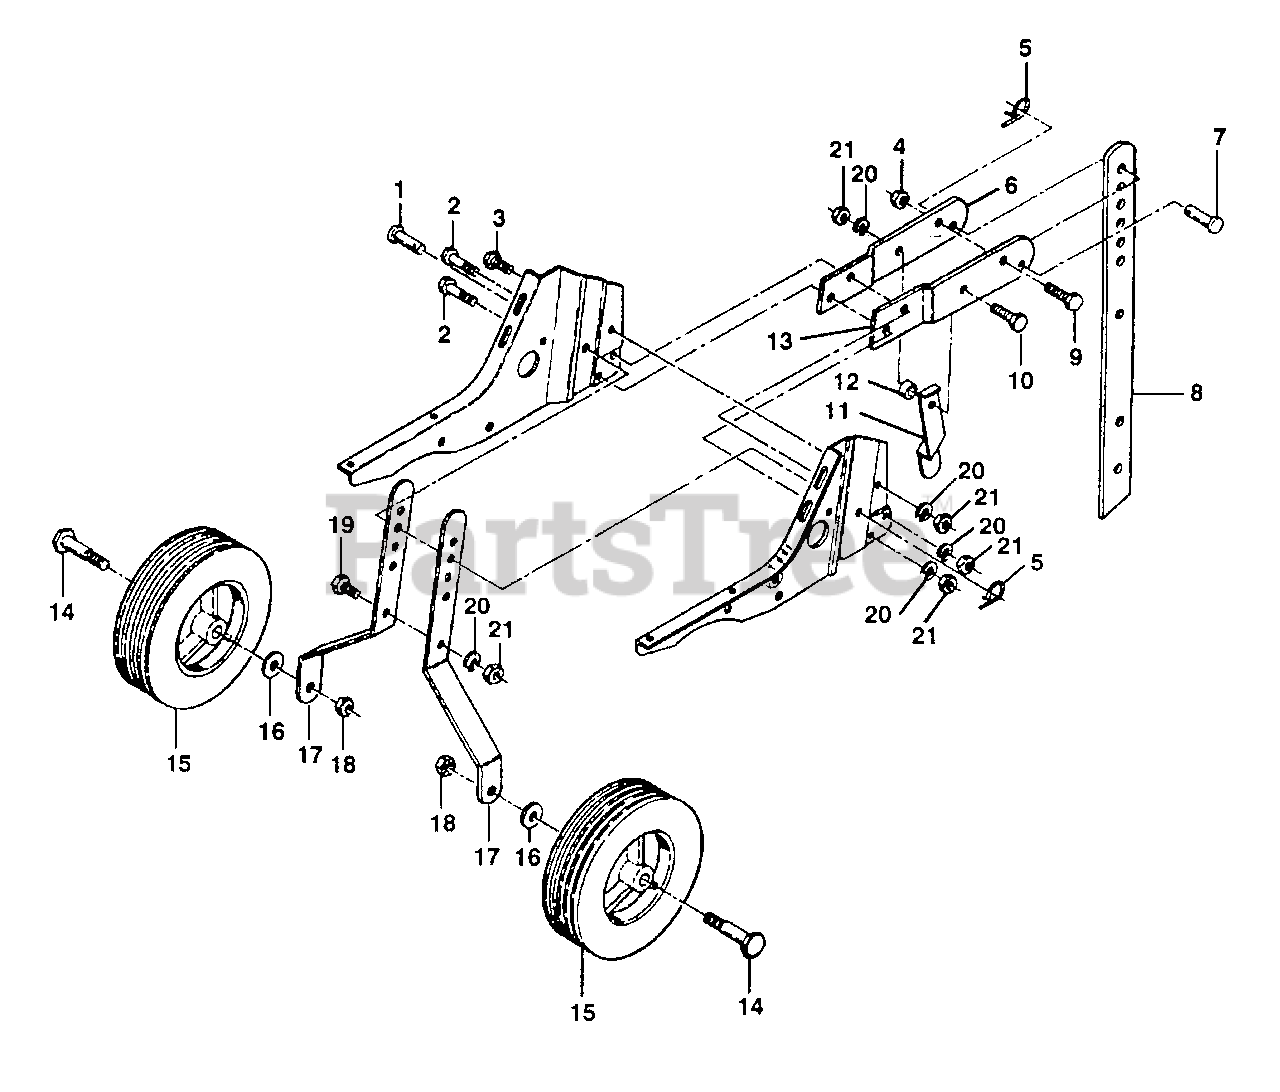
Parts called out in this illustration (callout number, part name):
1	Pin, Clevis (AYP part number)
2	Bolt, Hex 5/16-18 x 1-1/4 (AYP part number)
3	Bolt, Hex 5/16-18 x 3/4 (AYP part number)
4	Locknut 3/8-24 (AYP part number)
5	Clip, Hairpin (AYP part number)
6	Support, Depth Stake, R.H. (AYP part number)
7	Pin, Clevis (AYP part number)
8	Stake, Depth (AYP part number)
9	Bolt, Hex 3/8-24 x 1-1/2 Gr.5 (AYP part number)
10	Bolt, Hex 5/16-18 x 1-1/2 Gr.2 (AYP part number)
11	Spring, Stake (AYP part number)
12	Washer (AYP part number)
13	Support, Depth Stake, L.H. (AYP part number)
14	Bolt, Shoulder (AYP part number)
15	Wheel (AYP part number)
16	Washer 13/32 x 13/16 x 11 Ga. (AYP part number)
17	Bracket, Wheel (AYP part number)
18	Locknut, Crown 3/8-16
19	Bolt, Hex 5/16-18 x 1 (AYP part number)
20	Washer, Lock 5/16 (AYP part number)
21	Nut, Hex 5/16-18 (AYP part number)
